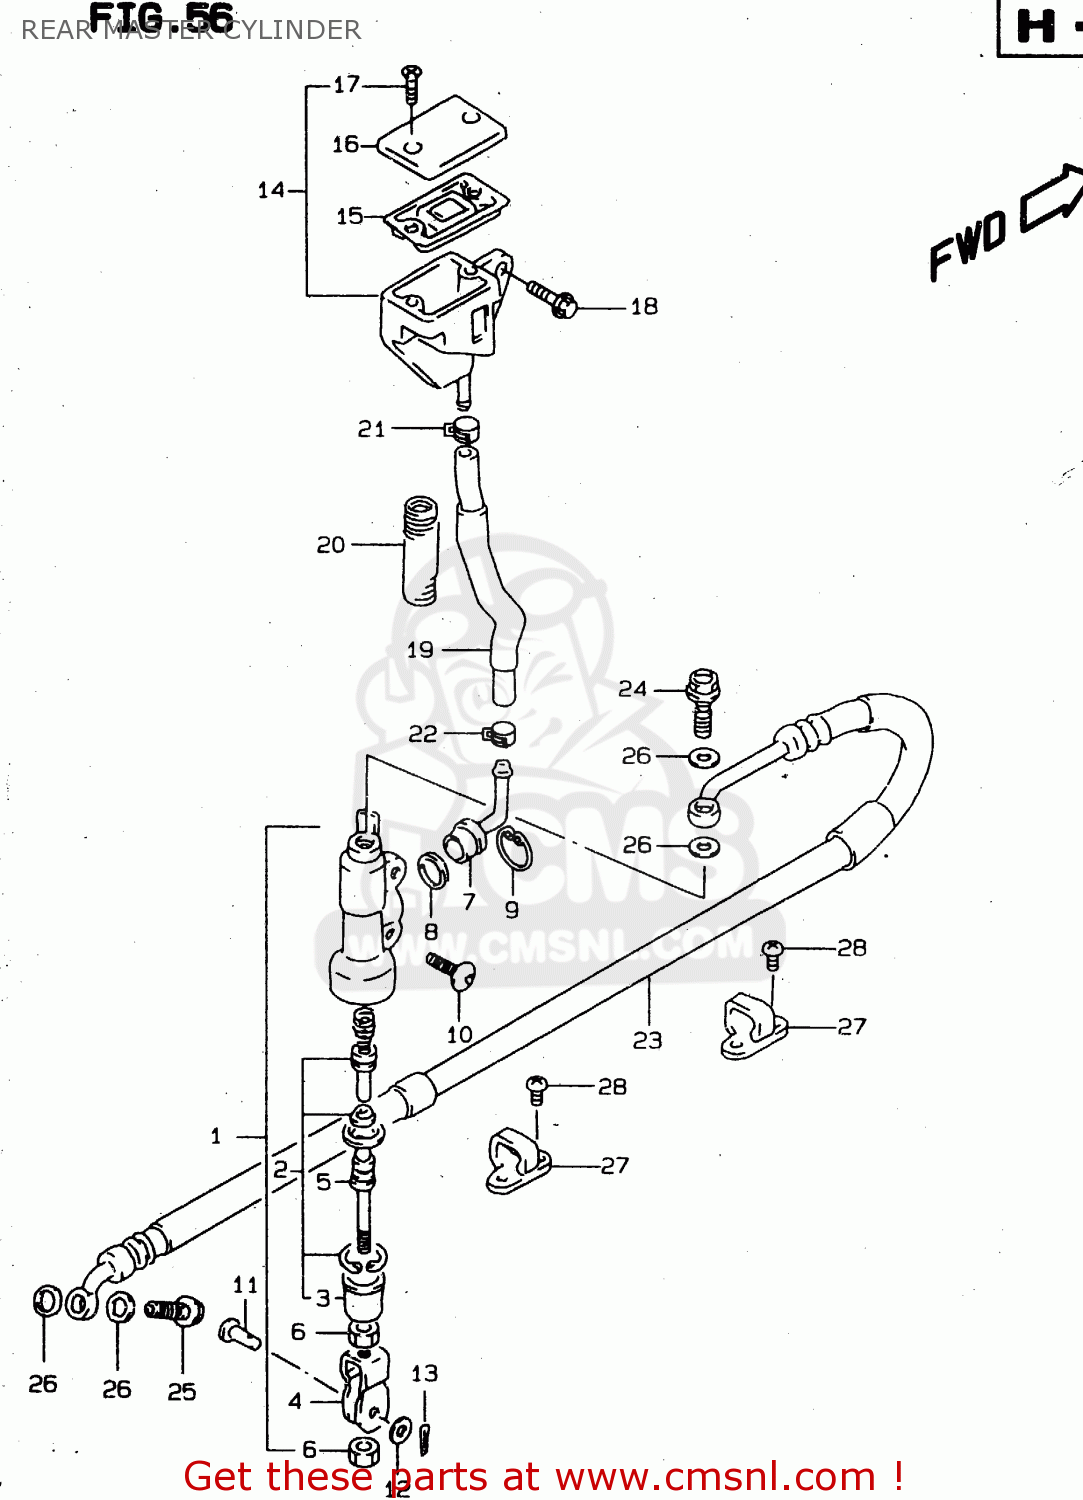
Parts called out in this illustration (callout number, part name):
1	CYLINDER ASSY,RR MASTER
2	PISTON/CUP SET
3	BOOT
4	YOKE
5	ROD,PUSH
6	NUT
7	CONNECTOR
8	O RING
9	CIRCLIP
10	SCREW(6X16)
11	PIN
12	WASHER
13	PIN
14	TANK ASSY,RR RESERVOIR
15	DIAPHRAGM
16	CAP
17	SCREW
18	BOLT
19	HOSE,RESERVOIR TANK
20	SHIELD,RSVR TANK HOSE HEAT
21	CLIP
22	CLIP
23	HOSE,RR BRAKE
24	BOLT UNION
25	BOLT UNION
26	WASHER(10X15X1.5)
27	GUIDE,RR BRAKE
28	SCREW
